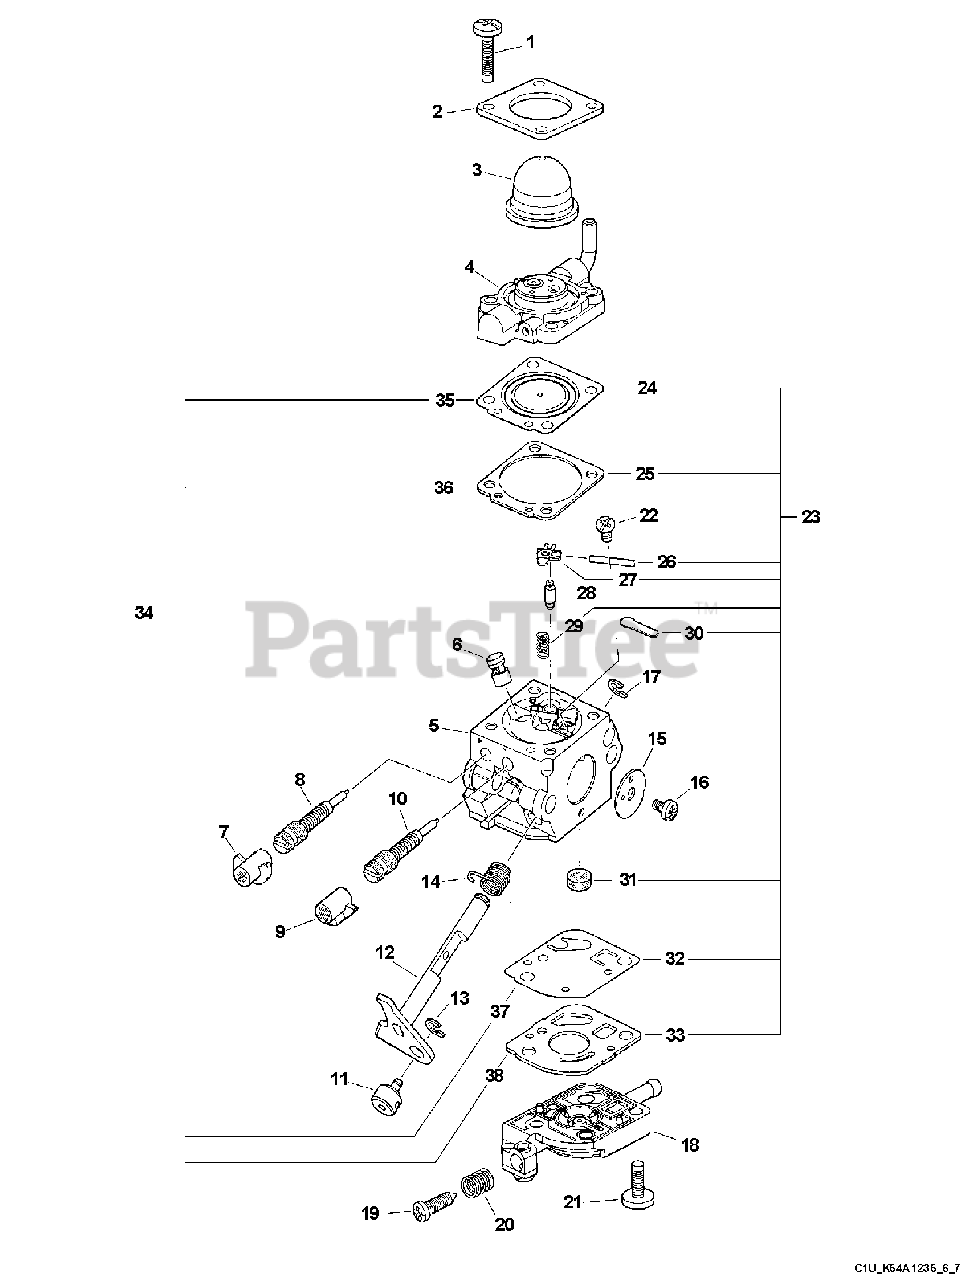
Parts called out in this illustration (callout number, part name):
2	RETAINER, PURGE BULB
3	BULB, PURGE
4	BASE, PURGE
5	BODY, CARBURETOR
6	NOZZLE, CHECK VALVE
7	CAP, LIMITER - RED
8	NEEDLE, HIGH SPEED
9	CAP, LIMITER - WHITE
10	NEEDLE, MIXTURE
12	SHAFT, THROTTLE
14	SPRING, THROTTLE RETURN
15	VALVE, THROTTLE
18	COVER, FUEL PUMP
19	SCREW, THROTTLE ADJUST
23	REBUILD KIT
24	DIAPHRAGM, METERING
25	GASKET, DIAPHRAGM
26	PIN, METERING LEVER
27	LEVER, METERING
28	VALVE, INLET NEEDLE
29	SPRING, METERING LEVER
30	PLUG, WELCH
31	STRAINER
32	DIAPHRAGM, PUMP
33	GASKET, PUMP
34	GASKET / DIAPHRAGM KIT
35	DIAPHRAGM, METERING
36	GASKET, DIAPHRAGM
37	DIAPHRAGM, PUMP
38	GASKET, PUMP
